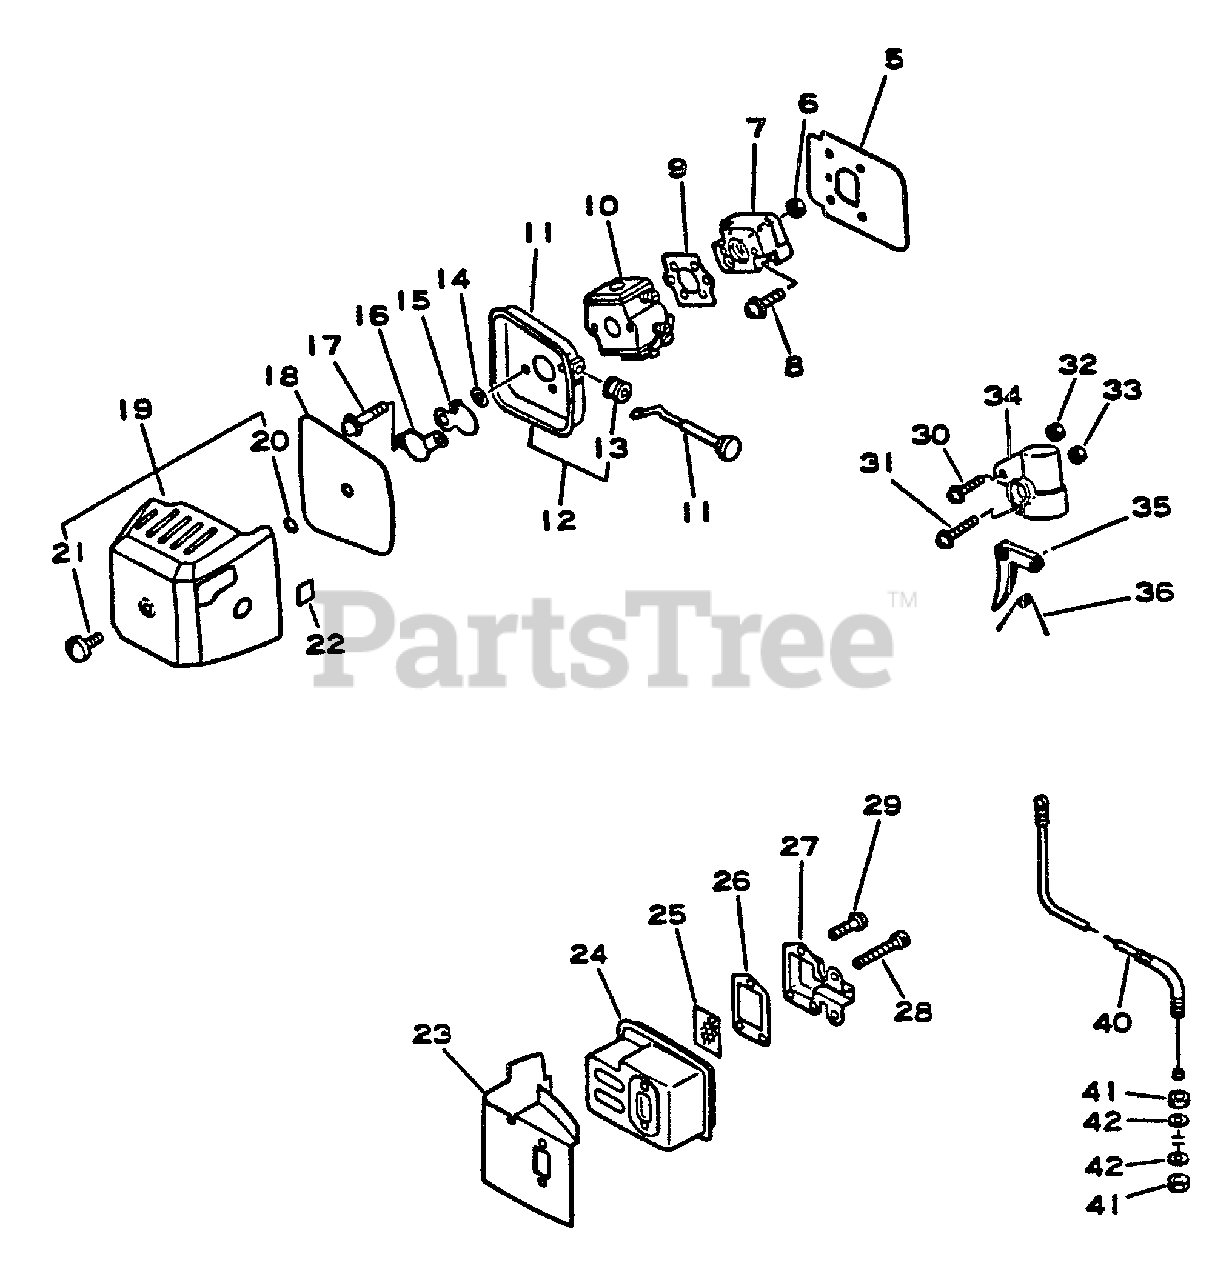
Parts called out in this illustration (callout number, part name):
5	SHIELD, INTAKE
7	INSULATOR, INTAKE
8	SCREW - 5X20
9	GASKET, INTAKE
10	CARBURETOR C1U-K10
11	ROD, CHOKE
12	CASE, AIR FILTER
14	WASHER - 5
15	SHUTTER, CHOKE
16	BRACKET, AIR CLEANER
17	SCREW - 5X57
18	FILTER, AIR
19	AIR FILTER COVER ASSY
20	O-RING - 4
22	LABEL - CHOKE
23	COVER, EXHAUST
25	SCREEN, SPARK ARRESTOR
26	GASKET, EXHAUST
27	GUIDE, EXHAUST
28	SCREW - 5X50
29	SCREW - 4X10
30	SCREW - 5X28
31	SCREW - 5X30
33	LOCKNUT - 5
34	BRACKET, TRIGGER
35	TRIGGER, THROTTLE
36	SPRING, TRIGGER
40	CABLE, THROTTLE
40	CABLE, THROTTLE - B
42	WASHER - 6
